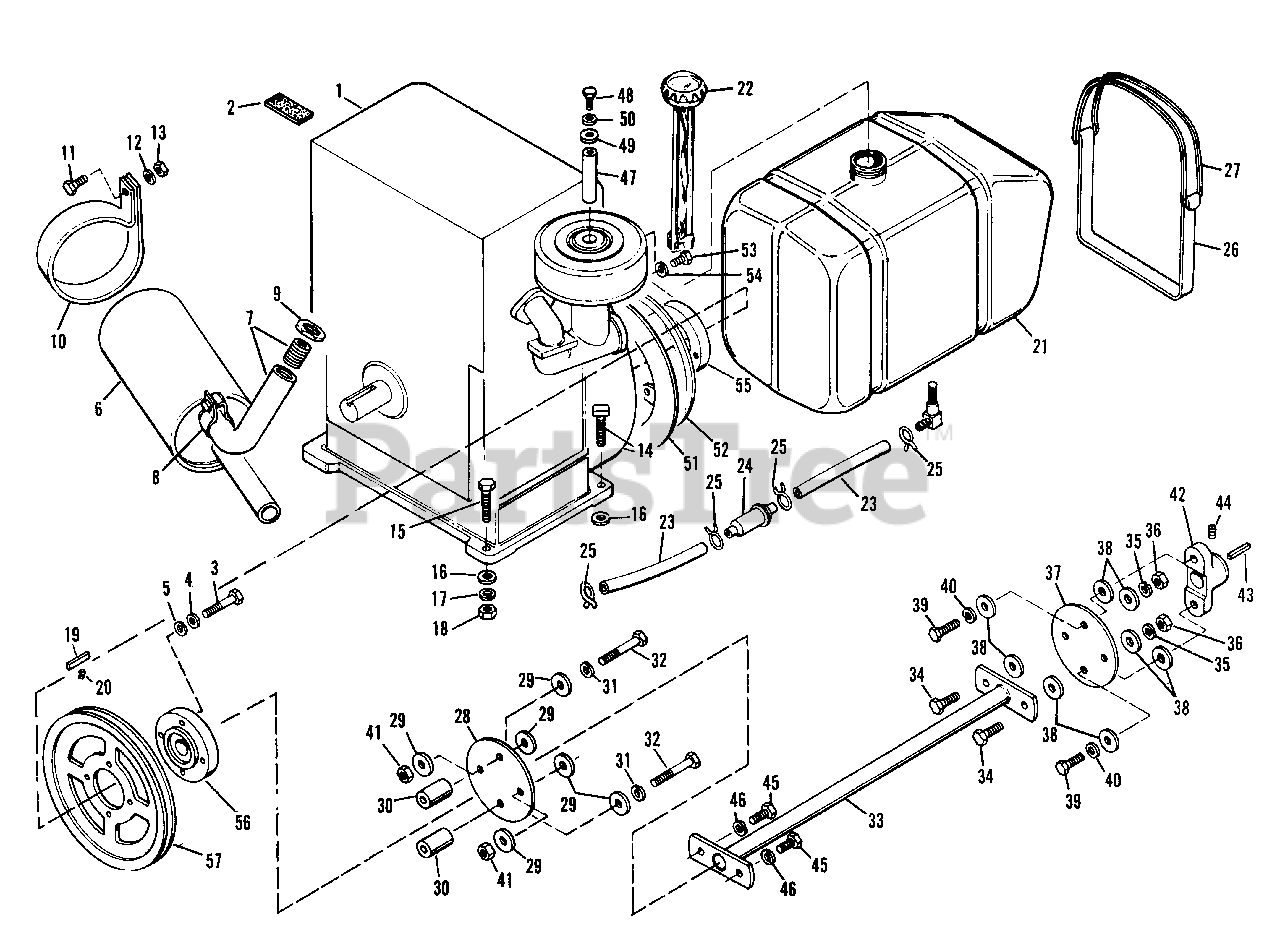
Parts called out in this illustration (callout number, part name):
2	Pad, Fuel Tank
3	* Hex Cap Screw, 5/16"-18 x 2"
4	* Plain Washer, 5/16 "
5	* Lock Washer, 5/16"
6	Muffler, Exhaust
7	Elbow & Nipple Assy.
8	Muffler Clamp
10	Strap, Muffler
11	Hex Cap Screw, 5/16"-18 N.C.x 5/8"
12	Lock Washer, 5/16"
13	Hex Nut, Full, 5/16"-18 N.C.
14	Rec't. Head Screw, 3/8"- 16 N.C. x 1-5/16"
15	Hex Cap Screw, 3/8"-16 N.C. x 1-1/2"
16	Plain Washer, 3/8" Std.
17	Lock Washer, 3/8"
18	Hex Nut Full, 3/8"-16 N.C.
19	KEY, Hi-Pro
20	Cup Pt. Socket Head Set Screw, 5/16"-18 N.C. x 5/8"
21	Tank, Fuel
22	Cap, Fuel Tank
23	Hose, Fuel, Flexible
24	Fuel Filter
25	Clamp, Hose
26	Strap, Tank
27	Strap, Fuel Tank
29	Washer, Special
30	Bearing, Pivot Block
31	Lock Washer, 3/8"
32	Hex Cap Screw, 3/8"-16x2-1/4"
33	Shaft Assy., Drive
34	Hex Cap Screw, 3/8"-16 x 1-1/8"
35	Lock Washer, 3/8"
36	Hex Full Nut, 3/8"-16
38	Washer, Special
39	Hex Cap Screw, 3/8"-16 N.C. x 1-1/8"
40	Lock Washer, 3/8"
41	Hex Nut, Full, 3/8"-16 N.C.
42	Flange, Drive Shaft
43	Key, Drive Shaft
44	Cup Pt. Socket Head Set Screw, 3/8"-24 N.F. x 3/8"
45	Hex Cap Screw, 3/8"-16 N.C. x 1-1/8"
46	Lock Washer, 3/8"
47	Air Cleaner Spacer
48	Hex Cap Screw, 1/4"-20 N.C. x 5/8"
49	Plain Washer, 1/4"
50	Lock Washer, 1/4"
51	* Flywheel Shroud
53	* Hex Capscrew 1/4"-20 x 1/2"
54	* Lock Washer, 1/4"
56	* Engine Pulley
57	* Drive Hub
